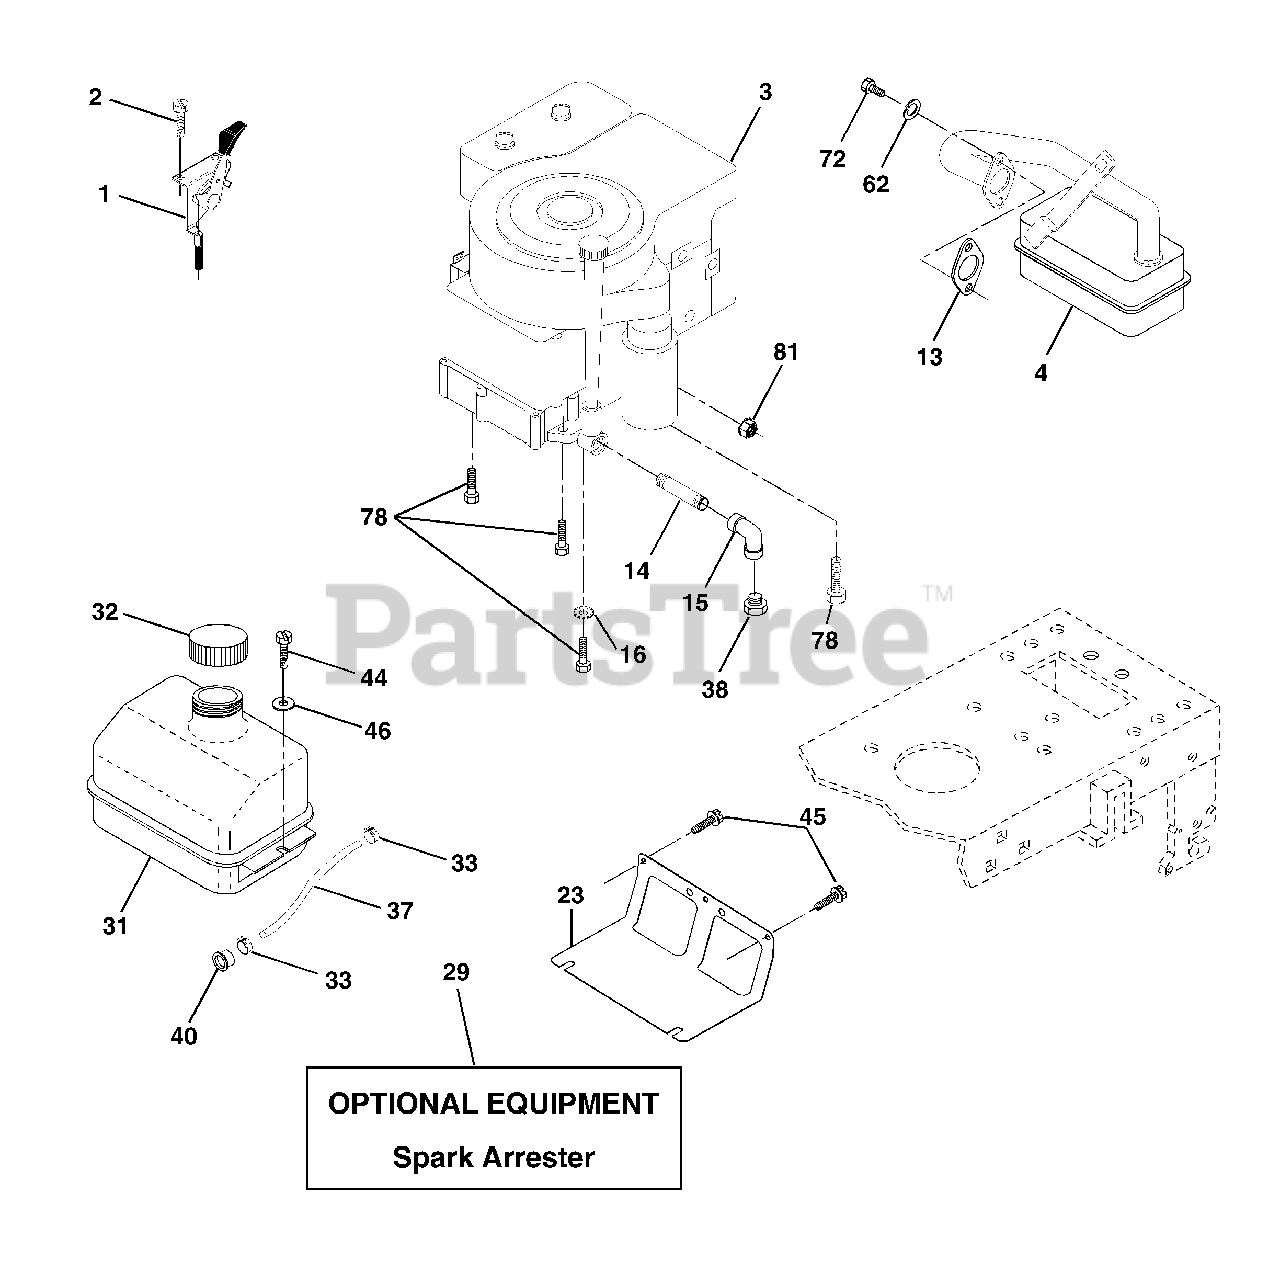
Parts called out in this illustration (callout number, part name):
1	Control Th/ch Flag
2	Screw Hex Thd Cut 1/4-20 x 1/2
4	Muffler Exhaust B&S
13	Gasket Eng 1 313 Id Tin Plated
14	Nipple Pipe 3/8 NPT x 3
15	Elbow Std 90 Degree 3/8-18 NPT
16	Washer Lock Ext Tooth 3/8
23	Shield BRN/DBR Guard
29	Kit Spark Arrestor (Flat Scrn)
31	Tank Fuel Front
32	Cap Asm Fuel
33	Clamp Hose
37	Line Fuel 20"
38	Plug Drain Oil
40	Bushing Snap Nyl Blk Fuel Line
44	Screw Thdrol 1/4-20 x 3/4
45	Screw Hex Wsh Thdrol 3/8-16
46	Washer 9/32 X 7/8 X 16 Ga
62	Washer Lock Hvy Hlcl Spr
72	Screw Hexcap 5/16-18 x 3/4
78	Screw 3/8-16 x 1-1/4
81	Nut Keps Hex 1/4-20 Unc
